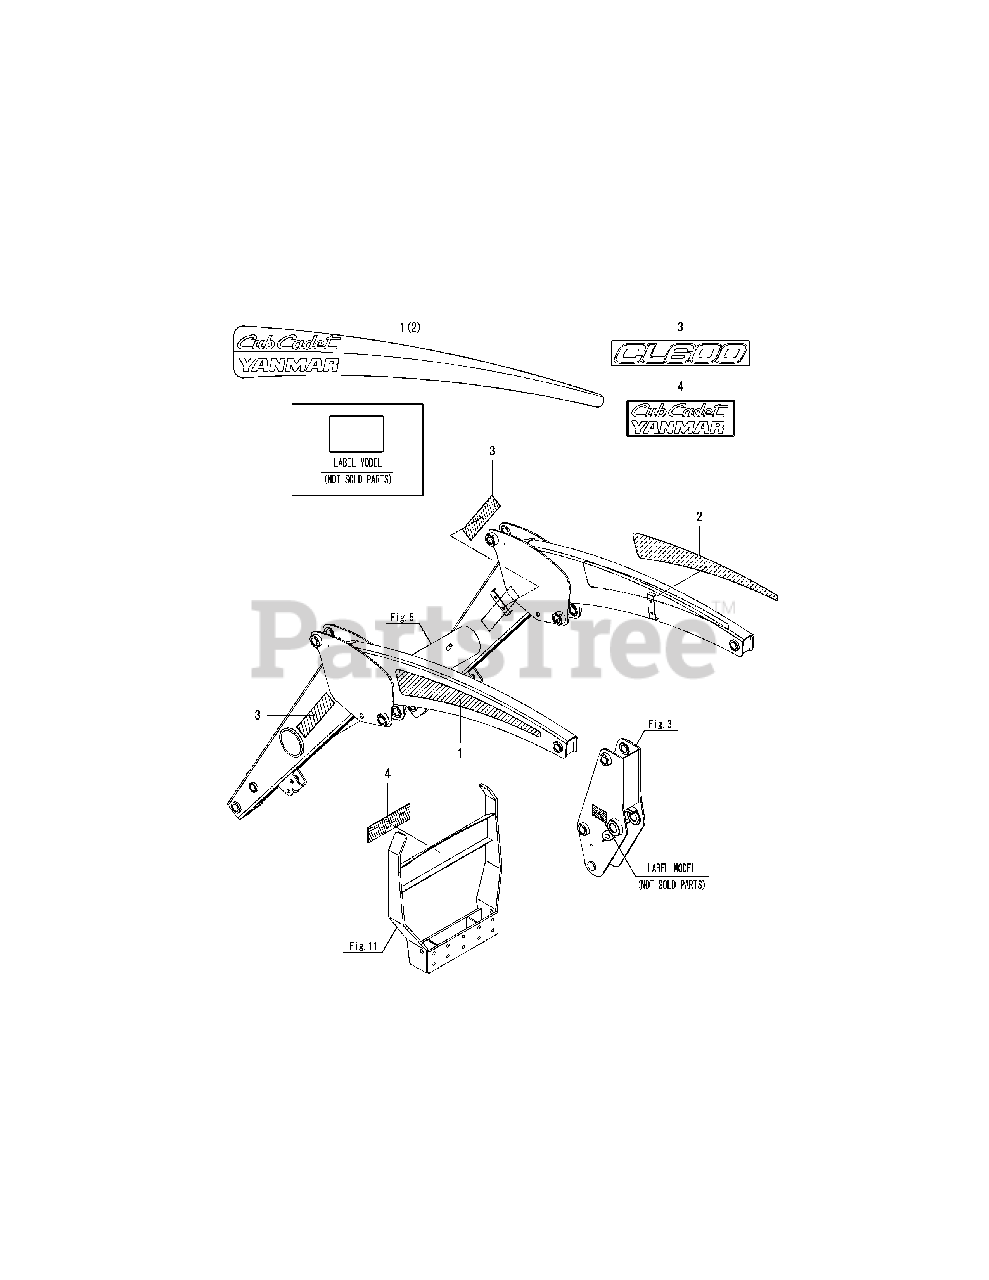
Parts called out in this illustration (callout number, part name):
1	LABEL,LOGO L.H.
2	LABEL,LOGO R.H.
3	LABEL, NAME CL600
4	LABEL, GRILL GAURD
